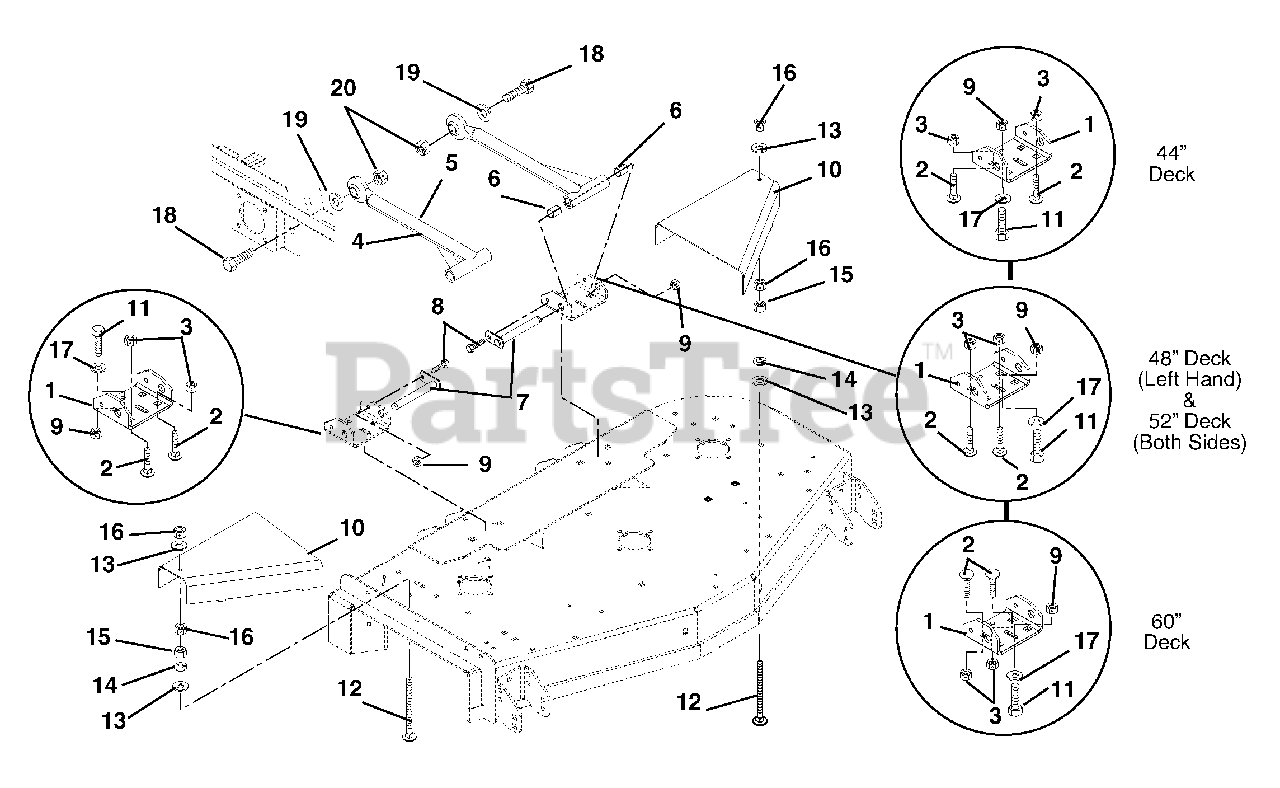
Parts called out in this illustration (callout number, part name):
1	Bracket, Mower Mounting (Rear)
2	Bolt, Round Head Square Neck .50-13 x .75 Grade 5
3	Nut, Locking Center Jam .50-13
4	Assembly, Mower Mounting
5	Mower Mounting Arm
6	Bearing, .75 x .875 x 1.00
7	Weldment, Mower Mounting Pin
8	Bolt, Hex .38-16 x .75 Grade 5
9	Nut, Locking Top Flange .38-16
10	Guard, Pulley Left Hand (044, 054)
10	Guard, Pulley Right Hand (044, 054)
10	Guard, Pulley Left Hand (051, 055)
10	Guard, Pulley Right Hand (051, 055)
10	Guard, Pulley (042, 043)
11	Bolt, Round Head Square Neck .38-16 x .75 Grade 5
12	Bolt, Round Head Square Neck Full Thread .312-18 x 3.50 (042, 043, 044, 054, 310, 311)
12	Bolt, Round Head Square Neck Full Thread .312-18 x 3.50 (051, 055)
13	Washer, Flat Steel .344 x .688 x .065 (042, 043, 044, 054, 310, 311)
13	Washer, Flat Steel .344 x .688 x .065 (051, 055)
14	Washer, Locking .31 x .078 (042, 043, 044, 054, 310, 311)
14	Washer, Locking .31 x .078 (051, 055)
15	Nut, Hex .31-18 (042, 043, 044, 054, 310, 311)
15	Nut, Hex .31-18 (051, 055)
16	Nut, Locking Center .31-18 (042, 043, 044, 054, 310, 311)
16	Nut, Locking Center .31-18 (051, 055)
17	Washer, Flat Steel .406 x .812 x .065
18	Bolt, Hex .875-9 x 2.75 Grade 5
19	Washer, Flat Steel .875 x 1.50 x .120
20	Nut, Locking Center .875-9
